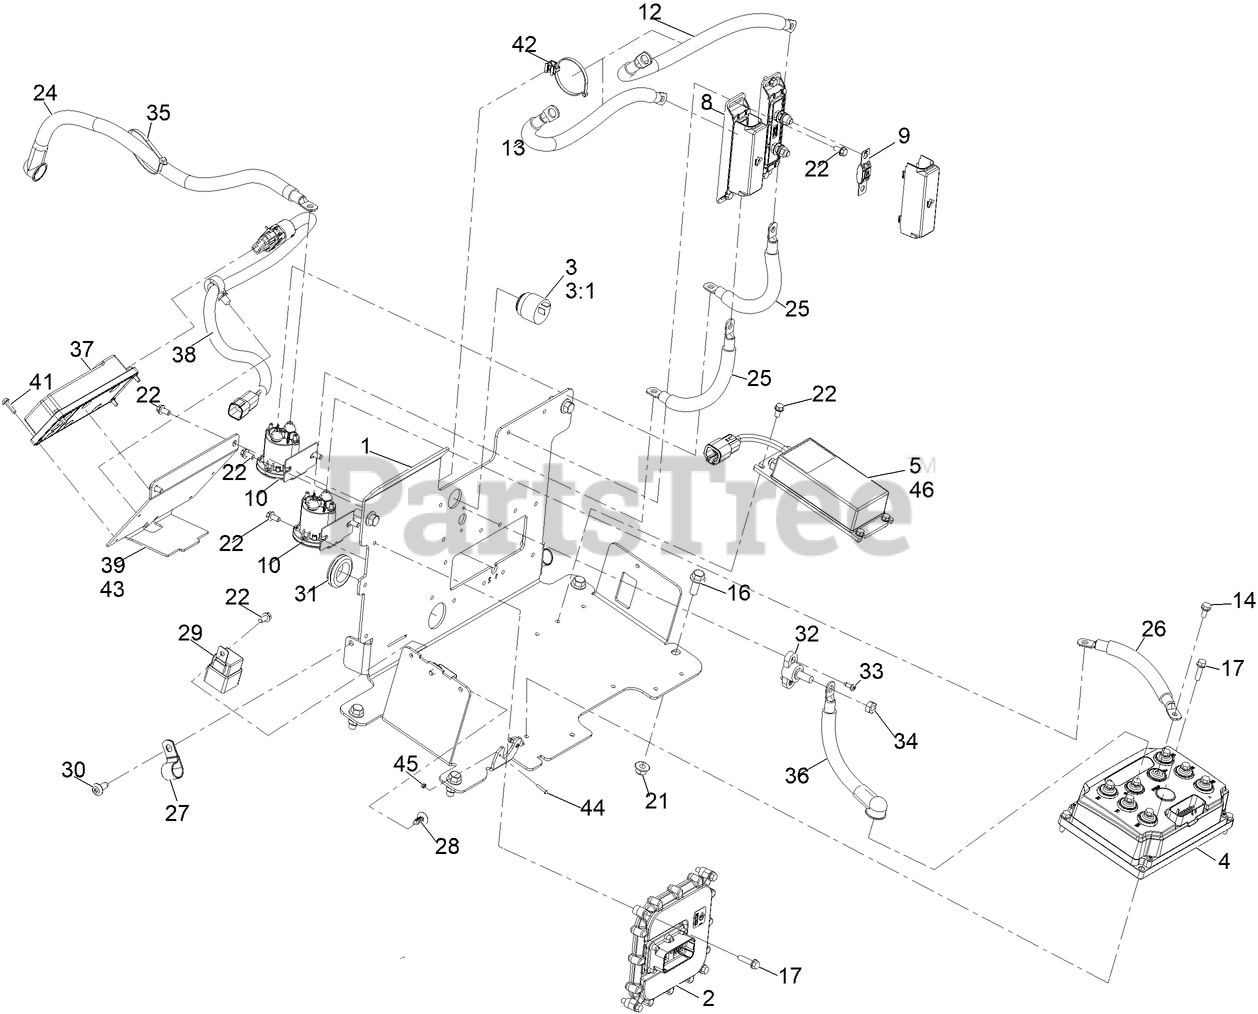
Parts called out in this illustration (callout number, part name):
1	PLATE-MNT, ELECTRICAL
2	CONTROLLER
3	Audio Alarm ASM
3:1	Nut-Plastic, Knurled
4	INV/CTRLR-48V,DUAL 94ARMS
5	CONVERTER DC-DC
8	HOLDER-FUSE
9	FUSE-200A
10	CONTACTOR-DC, 12V
12	CABLE-BATTERY, RD ASM
13	CABLE-BATTERY, RD ASM
14	SCREW-SEMS
16	SCREW-HHF 3/8-16 X 1
17	SCREW-HWHTF
21	NUT-HF, NI
22	SCREW-HWH
24	CABLE-BATTERY, RD ASM
25	CABLE-BATTERY, RD ASM
26	CABLE-BATTERY, RD ASM
27	CLAMP-R
28	PLUG-PLASTIC
31	GROMMET
32	BLOCK-JUNCTION
33	SCREW-FORMING, THREAD
34	NUT-HEX
35	TIE-CABLE
36	CABLE-BATTERY, BK ASM
37	CONTROLLER
38	HARNESS-WIRE
39	BRKT-MODULE MNT
41	SCREW-HWH
42	CLIP-HARNESS. EDGE, W/TIE-WRAP
43	NUT-CLIP, U
44	SCREW-PPH
45	NUT-HEX, NYL INS
46	FERRITE, SNAP-ON
